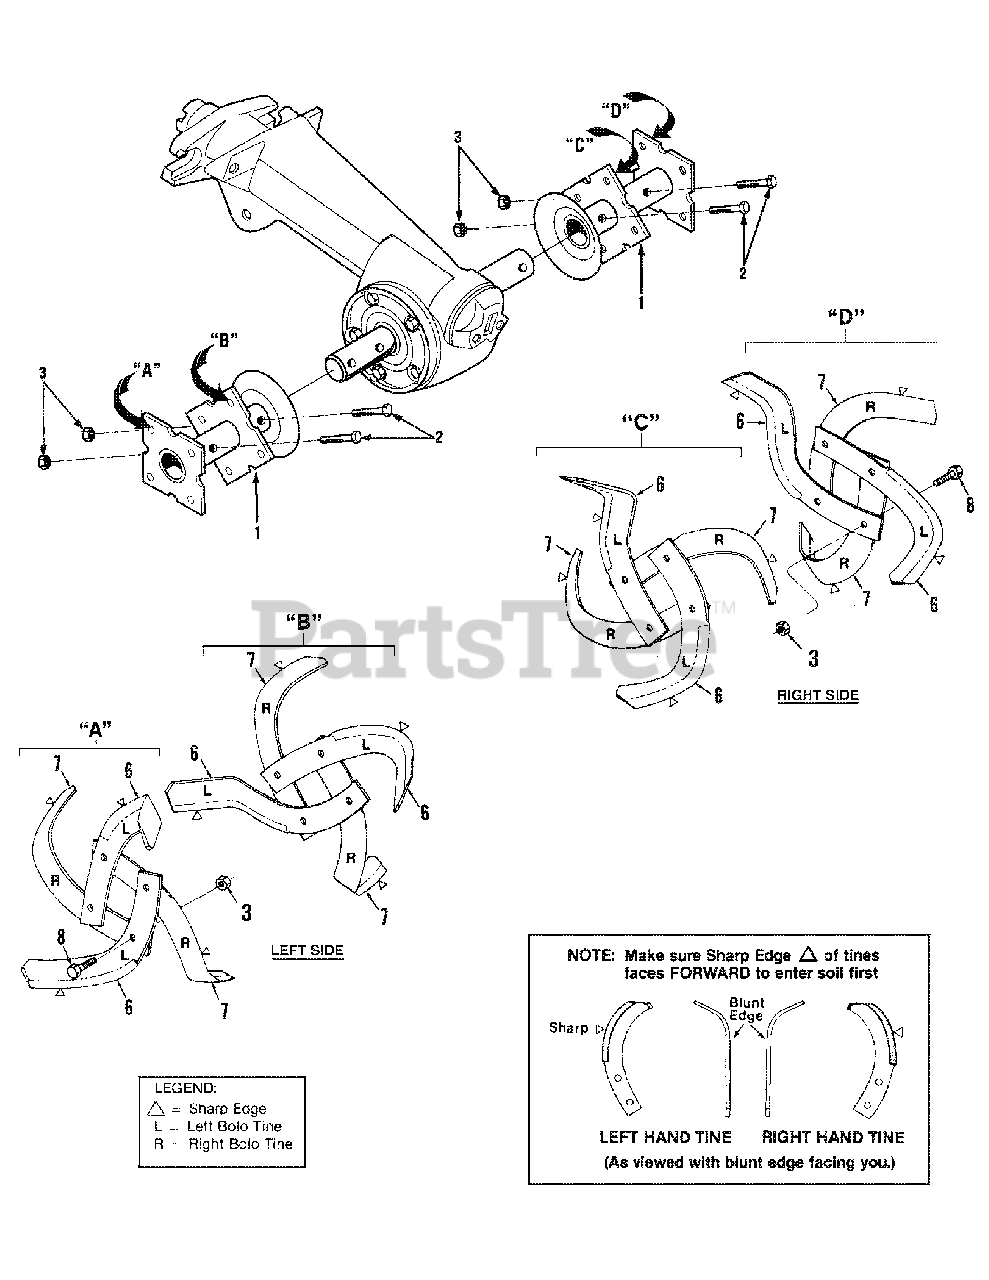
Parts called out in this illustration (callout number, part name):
1	Tine Holder-welded steel, fits left or right sides
2	Bolt-hex hd., 3/8-16 x 2"
3	Locknut-hex, 3/8"-16
6	Bolo Tine-single, left hand. Tine is stamped either "EL" or "AL"
7	Eolo Tine-single, right hand. Tine is stamped either "ER" or "AR"
8	Bolt-hes hd., 3/8-16 x 1"
